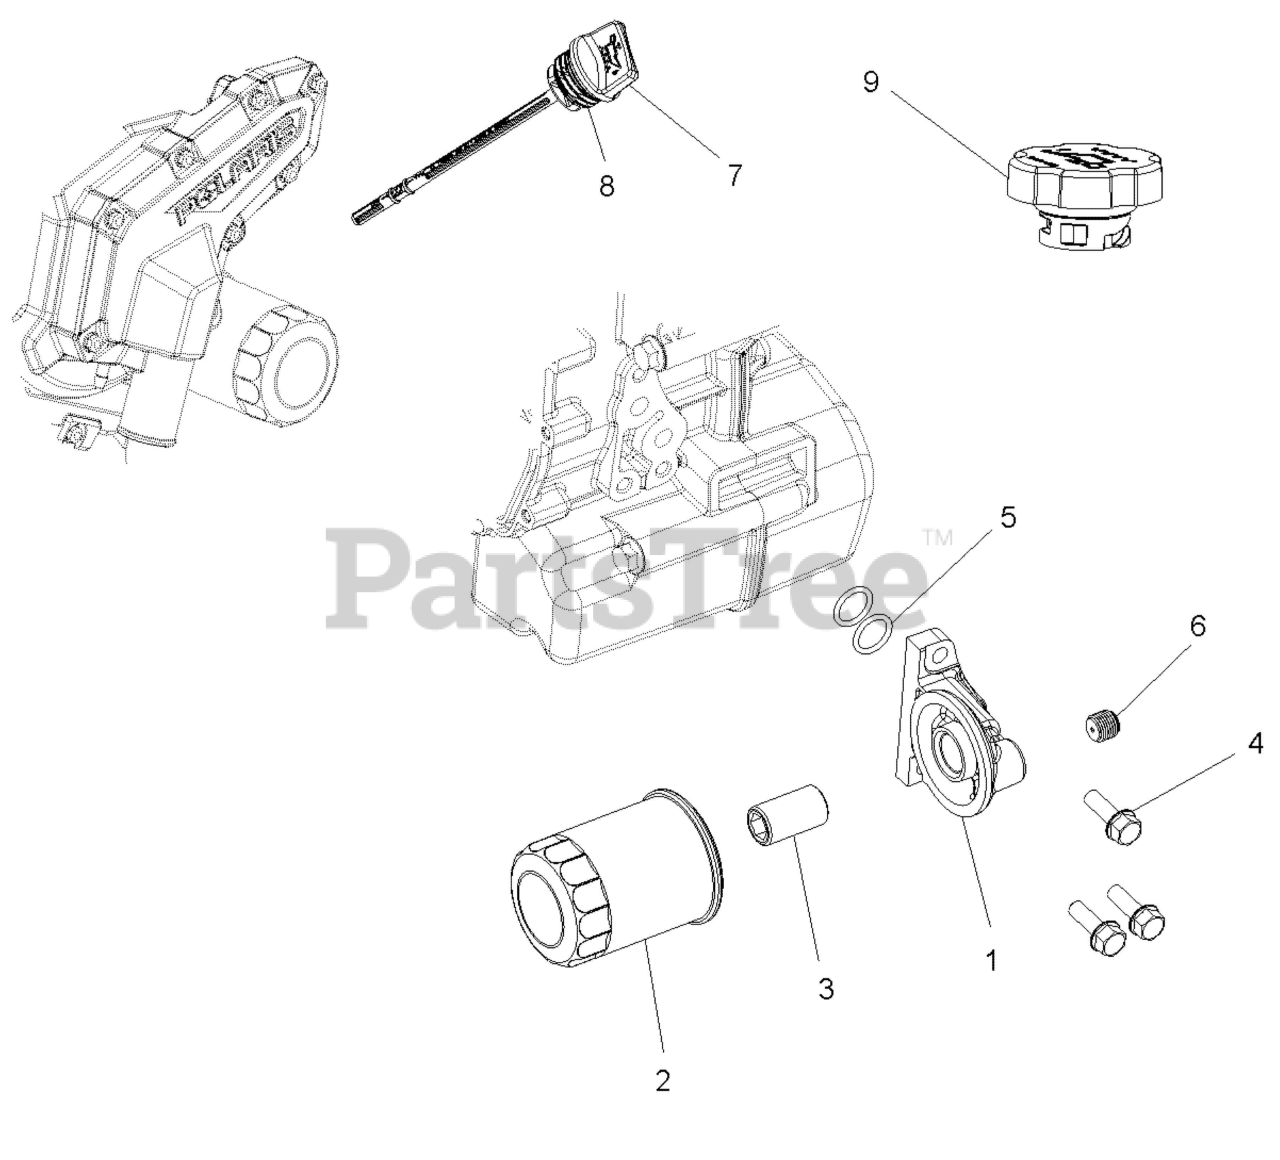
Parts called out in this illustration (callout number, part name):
1	ADAPTER, OIL FILTER, MACH
2	FILTER-OIL,10 MICRON,(12)
3	ADAPTOR, FILTER, STRAIGHT
5	O-RING-17.12X2.62
6	PLUG,HEX SCKT W/O-RING,M14X1.5
7	DIPSTICK-OIL FILL
8	O-RING-26.65X2.62,0600083
9	ASM-OIL FILL CAP
9	O-RING-FILL CAP
